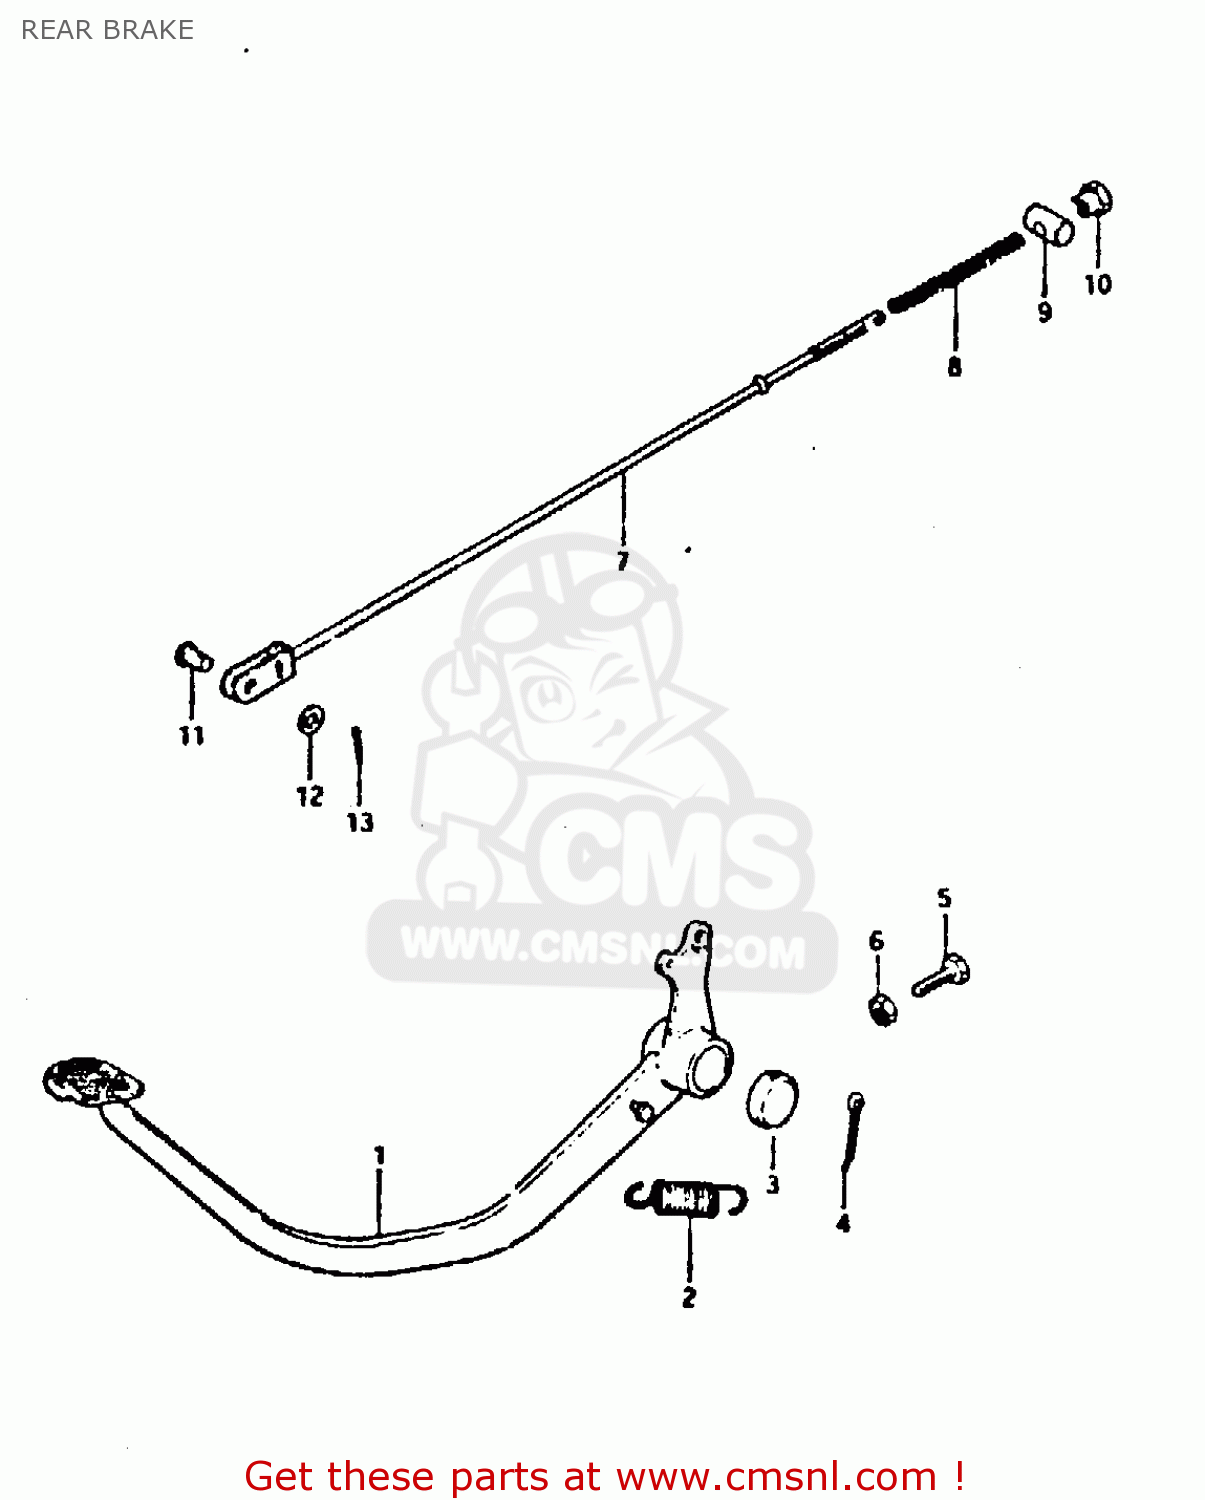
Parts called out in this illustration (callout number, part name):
1	PEDAL, BRAKE
2	SPRING
3	CAP,BRAKE PEDAL
4	PIN, COTTER
5	BOLT(6X25)
6	NUT
7	ROD,RR BRAKE
8	SPRING
9	PIN
10	NUT
11	PIN(L:13.5)
12	WASHER
13	PIN 20X20
